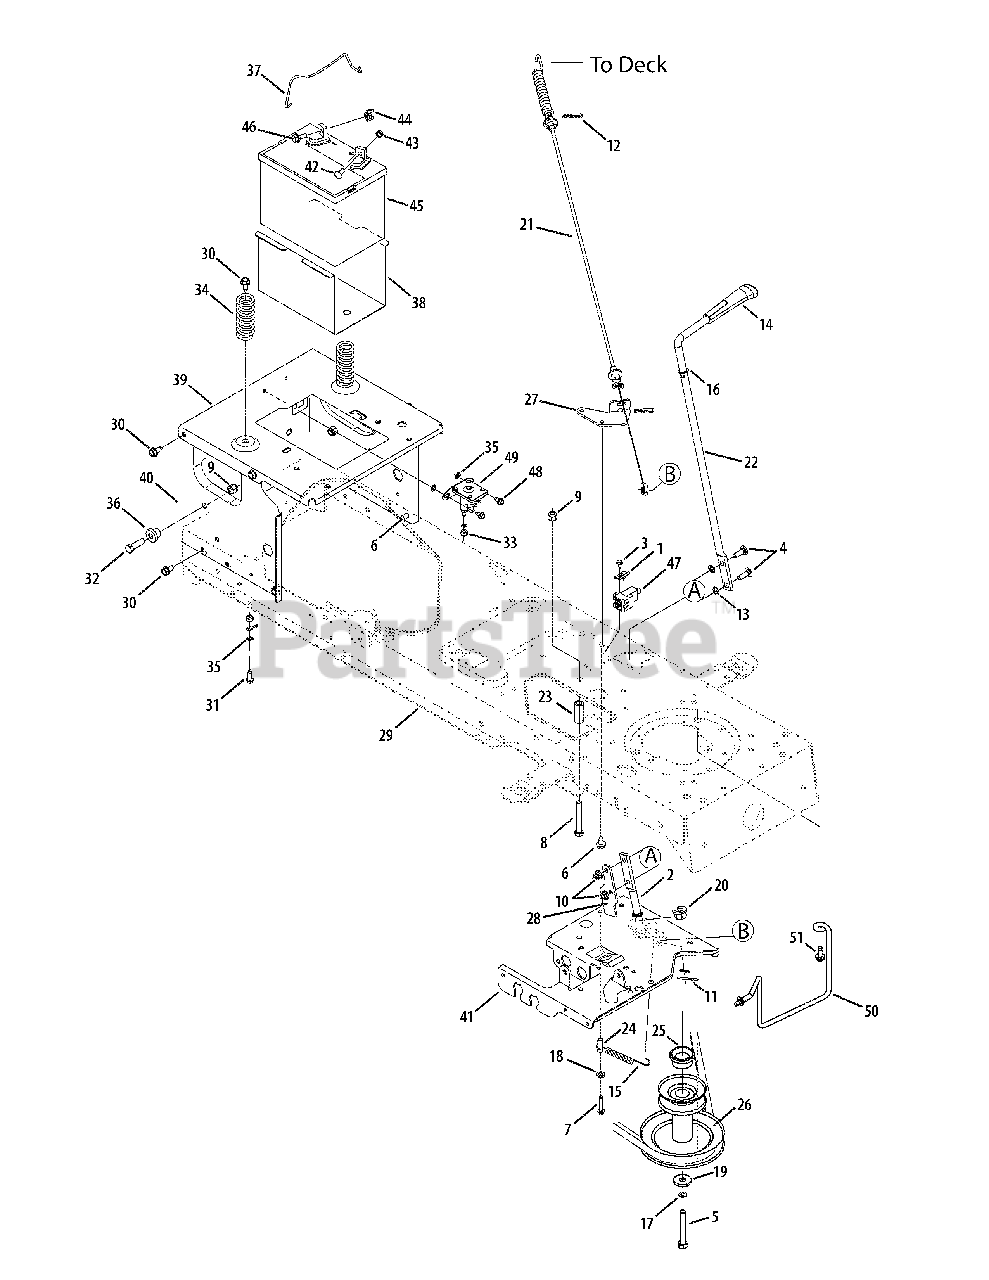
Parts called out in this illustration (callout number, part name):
1	Plate, Switch
2	Lever Assembly, Engagement
3	Screw, #10-16, 0.500
4	Screw, Carriage, 5/16-18, 1.00
5	Screw, 7/16-20, 3.25 42" Deck
6	Screw, 5/16-18, 0.500
7	Screw, 1/4-20 x 1.50
8	Screw, 3/8-16 x 2.25
9	Nut, Flange Lock, 3/8-16, GrF
10	Nut, Flange Lock, 5/16-18, Gr5
11	Pin, Cotter, 1/8 x 1.00
12	Click Pin
13	Nut, Speed, .3125 ID
14	Knob, PTO
15	Extension Spring, .38 OD x 3.9 Lg
16	Washer, Flat, .510 x .750 x .033
17	Washer, Lock, 7/16
18	Washer, Flat, .28 x .74 x .063
19	Washer, Flat, .450 x1.250 x.164
20	Bearing, Flange, Hex Split .500 ID
21	Deck Engagement Cable
22	Engagement Handle, Deck
23	Spacer, .385 ID x .635 OD x 1.54
24	Spacer, .260 x .372 x 1.030 Lg.
25	Spacer, 1.010 x 1.40 x .825
26	Pulley, Engine, 42" Deck
31	Screw, 1/4-20, 0.750
32	Screw, 3/8-16, 1.25, Gr5
33	Nut, Flange Lock, 1/4-20, GrF
34	Spring, Compr., 1.28 OD x 3.125
35	Washer, Lock, 1/4, External
36	Spacer, Shoulder, .38 x 1.0 x .70
37	Hold Rod, Battery
42	Hex Head Flange Screw
43	Nut, Sems, 1/4-20
44	Nut, Wing, 1/4-20
45	Battery, 190 CCA
46	Screw, Shoulder, .250 x .150
47	Switch, Interlock
48	Screw, 1/4-20, 0.50
49	Solenoid, 12V, 100 Amp
51	Screw, 5/16-18, .750
